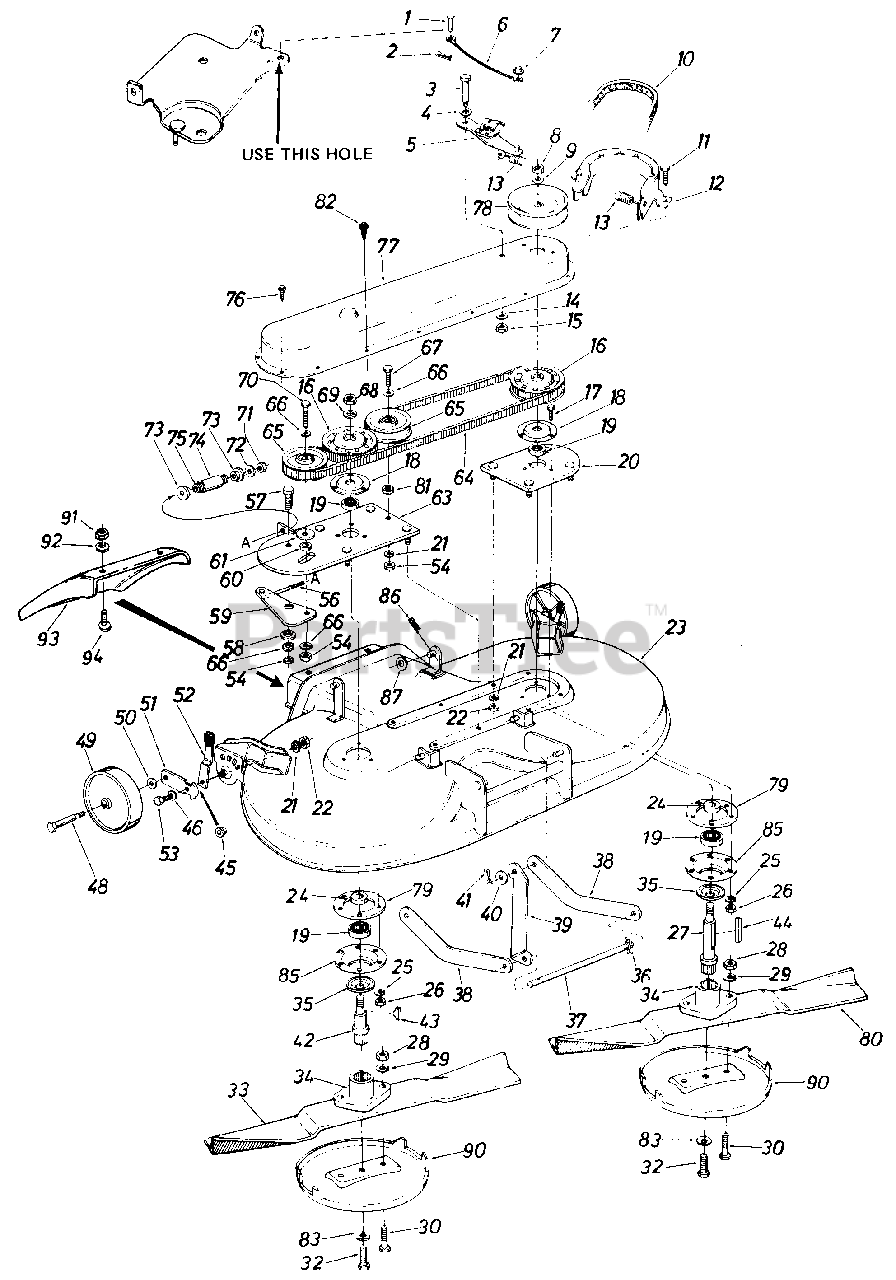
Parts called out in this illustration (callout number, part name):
1	Clevis Pin 1/4" Dia. x 1/2" Lg.
2	Hairpin Cotter 1/4" Dia.
3	Shld. Bolt .437" Dia. x .180" Lg. (5/16-18)
4	Wave Washer 7/16" Scr.
5	Spindle Brake Arm Ass'y.
6	Brake Cable Ass'y.
7	Push Cap 1/4" Stud.
8	Hex Jam Nut 5/8-18 Thd.
9	Bell.-Wash. 5/8" I.D. x 1.25" O.D.
10	"V"Belt
11	Hex Wash. Hd. Self Tap Scr. 1/4-20 x .50" Lg.
12	Belt Guard
13	Extension Spring
14	Bell.-Wash. .340" I.D.
15	Hex Cent. L-Nut 5/16-18 Thd.
16	Sprocket Pulley Ass'y.
17	Hex Bolt 5/16-24 x 1.00" Lg. (Grade 5)
18	Bearing Housing
19	Ball Bearing .787" I.D. x 1.85" O.D.
20	Spindle Plate Ass'y.
21	L.-Wash. 3/8" I.D.
22	Hex Jam Nut 3/5-"4 Thd.
23	44" R.C. Deck Ass'y.
25	L.-Wash. 5/16" I.D.
26	Hex Nut 5/16-24 Thd.
27	Blade Spindle-L.H.
28	Hex Nut 5/16-24 Thd.*
29	L.-Wash. 5/16" I.D.
30	Hex Bolt 5/16-24 x 1.00" Lg.
32	Hex Bolt Cent. L.-3/8 x 24 x 88" Lg.
33	22.5" Blade-L.H. Rotation
34	Blade Adapter
35	Bearing Shield
36	Hairpin Cotter
37	Deck Connecting Rod
41	Cotter Pin 3/32" Dia. x 1.00" Lg.*
42	Blade Spindle-R.H.
43	Sq. Key 3/16" x 75" Lg.
44	Sq. Key 3/16" x 1.50" Lg.
45	Shoulder Spacer
46	Bell.-Wash. .400" I.D.
48	Shld. Bolt 3/8-16 x 1.41" Lg.
49	Wheel Ass'y. Comp. 6" x 1.38
50	Bell-Wash. 3/8" I.D.
51	Wheel Pivot Bar
52	Spring Lever Ass'y. w/knob
53	Hex Bolt 3/8-24 x 1.25" Lg. Grade 5
54	Hex Cent. L-Nut 3/8-24 Thd.
56	Adjustment Link 5/16-18 x 4-9/16" Lg.
57	Hex Bolt 3/8-24 x 1.00"
58	Shld. Spacer .625" I.D.
59	Belt Idler Brkt
60	Spacer.380" I.D. x.625" O.D. x .265
61	Fl.-Wash. .38" I.D. x 1.37" O.D. x .125
63	Spindle & Idler Moun Plate Ass'y.
64	HTD Twin Power Belt
65	Fl.-ldler Pulley 3.50" O.D.
66	Bell.-Wash. .38" I.D.
67	Hex Bolt 3/8-24 x 1.75" Lg. (Grade 5)
68	Hex Jam Nut 5/8-18 Thd.*
69	Bell.-Wash. 5/8" I.D.
70	Hex Bolt 3/8-24 x 2.00" Lg.
71	Hex Insert L.-Nut 5/16-18 Thd.
72	Fl.-Wash. 344" I.D. x 1.125" O.D. x .125
73	Shld. Spacer.625" I.D.
74	Spacer-Adj. Bolt
75	Compression Spring
76	Hex Wash. Hd. Self Tap Scr. 1/4-20 x .50" Lg.
77	Belt Cover
78	Deck Drive Pulley
79	Deck Reinforcement Plate
80	22.5" Blade-R.H. Rotation
81	Fl.-Wash. .38" I.D. x 1.00" O.D.
82	Hex Wash. Hd. Self Tap-Scr. 1/4-20 x .75" 4.
83	L.-Wash. 3/8" I.D. Heavy Duty
86	Hairpin Cotter
87	Fl.-Wash. 1/2" I.D.
90	Anti Scalp Plate
91	Hex Nut 1/4-20 Thd.
92	L.-Wash. 1/4" I.D.
93	Chute Deflector
94	Truss Mach. Scr. 1i1-20 x .50" Lg.
